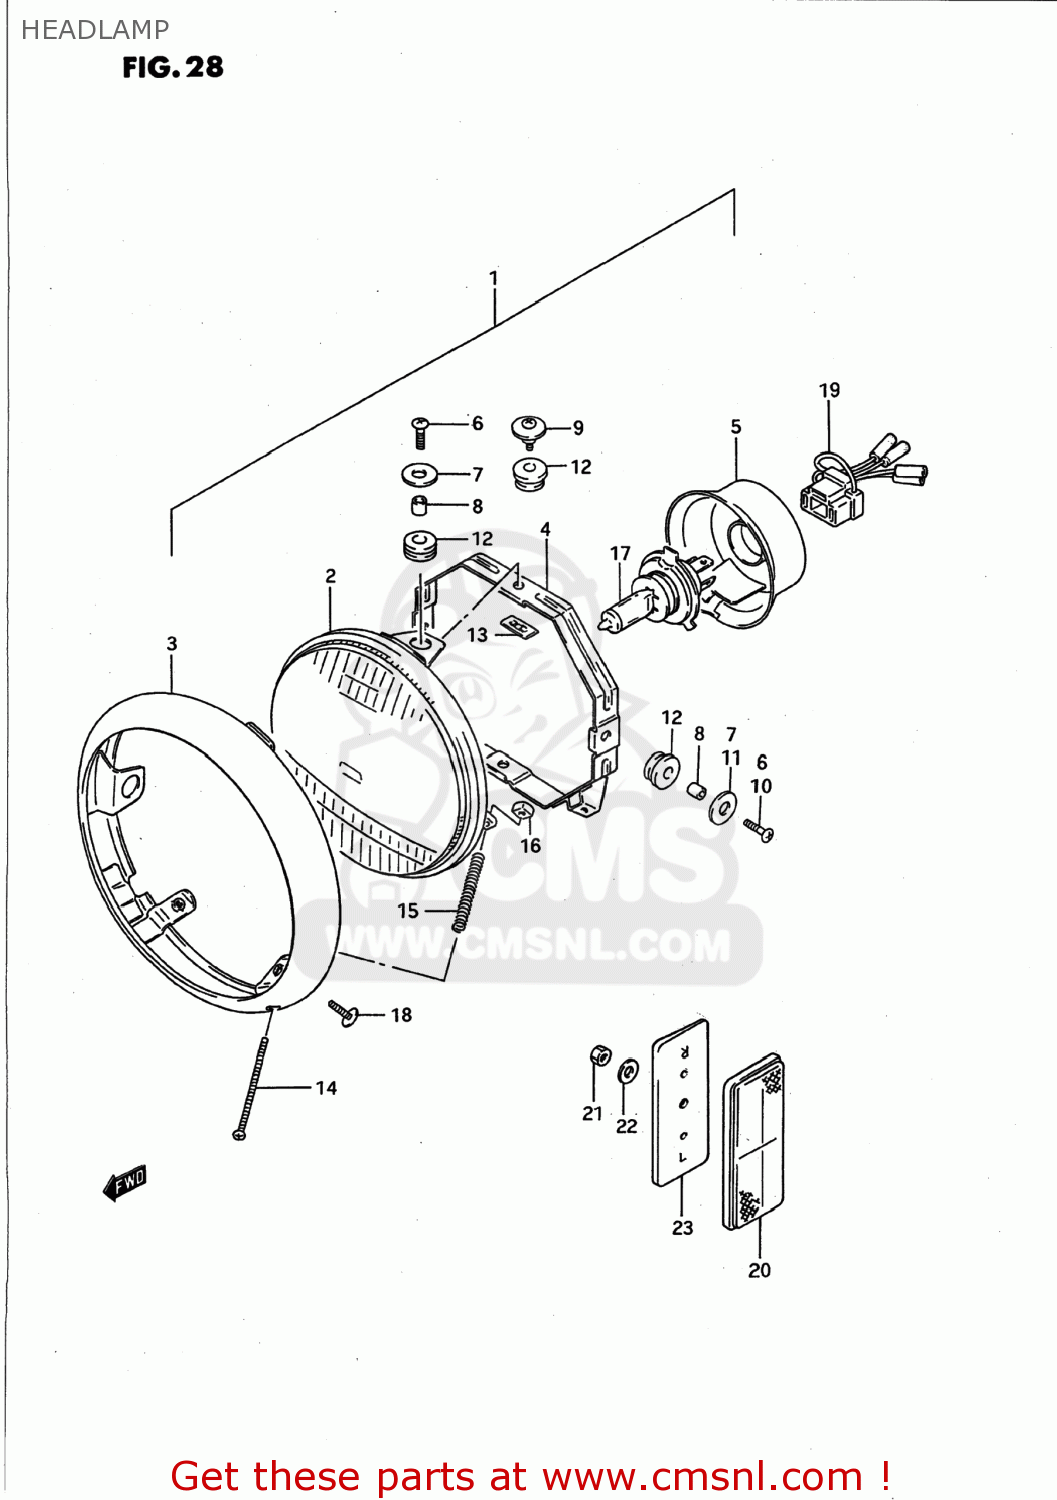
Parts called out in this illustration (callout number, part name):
1	HEADLAMP ASSY
2	UNIT,LAMP
3	RIM
4	RING,MOUNTING
5	COVER,SOCKET
6	SCREW
7	WASHER
8	SPACER
9	SCREW,MOUNTING
10	SCREW
11	WASHER (5.5X18X1)
12	CUSHION
13	NUT
14	SCREW,HEADLAMP ADJUST
15	SPRING
16	NUT
17	BULB(12V60/55W,H4)
18	SCREW
19	WIRE
20	REFLEX REFLECTOR ASSY,FR SIDE
21	NUT
22	WASHER
23	SPACER,FR SIDE RR
